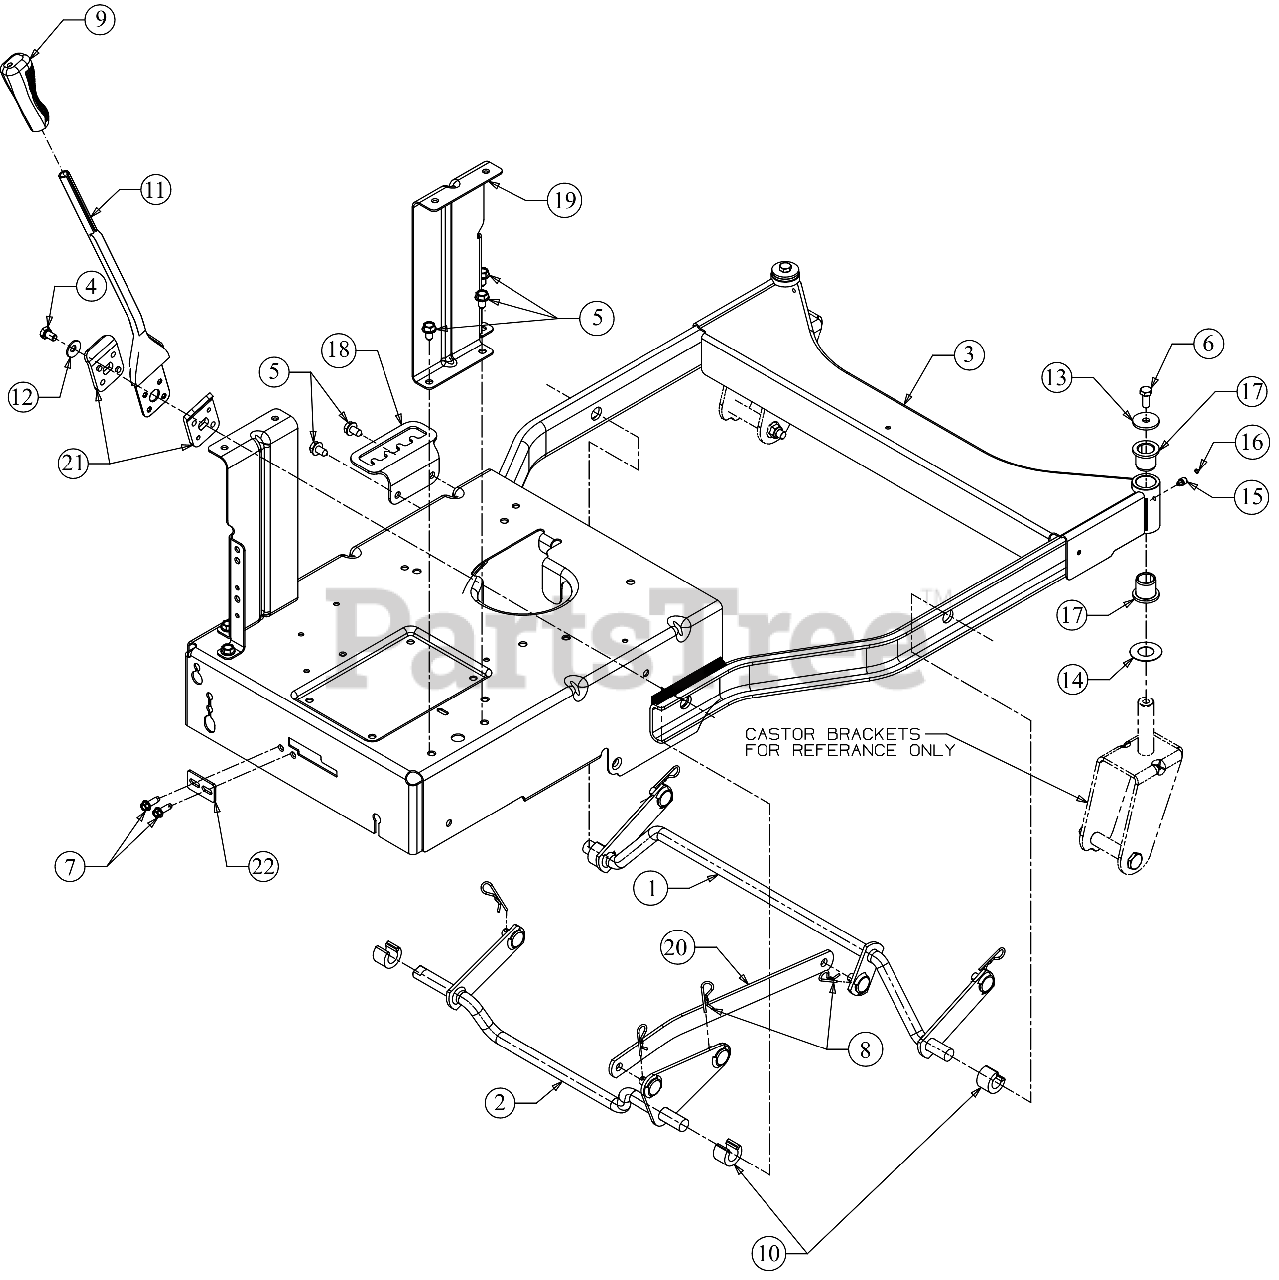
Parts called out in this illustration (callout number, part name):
1	FRONT LIFT ASSEMBLY
2	DECK LIFT ASSEMBLY
4	SCREW 5/16-18 X .50
5	SCREW 5/16-18 X .625
6	SCREW 5/16-24 X .750 GR5
7	SCREW 1/4-20 X .750
8	INTERNAL COTTER PIN
9	HANDLE GRIP
10	SNAP SPACER
11	DECK HEIGHT LEVER
12	BELL WASHER .337 X.867 X .057
13	WASHER-5/16 X 1.25X 1.27
14	THRUST WASHER
15	GREASE FITTING
17	FLANGE BEARING .760 ID
20	LIFT LINK
21	HEIGHT LEVER BRACKET
22	SHIFT PLATE
